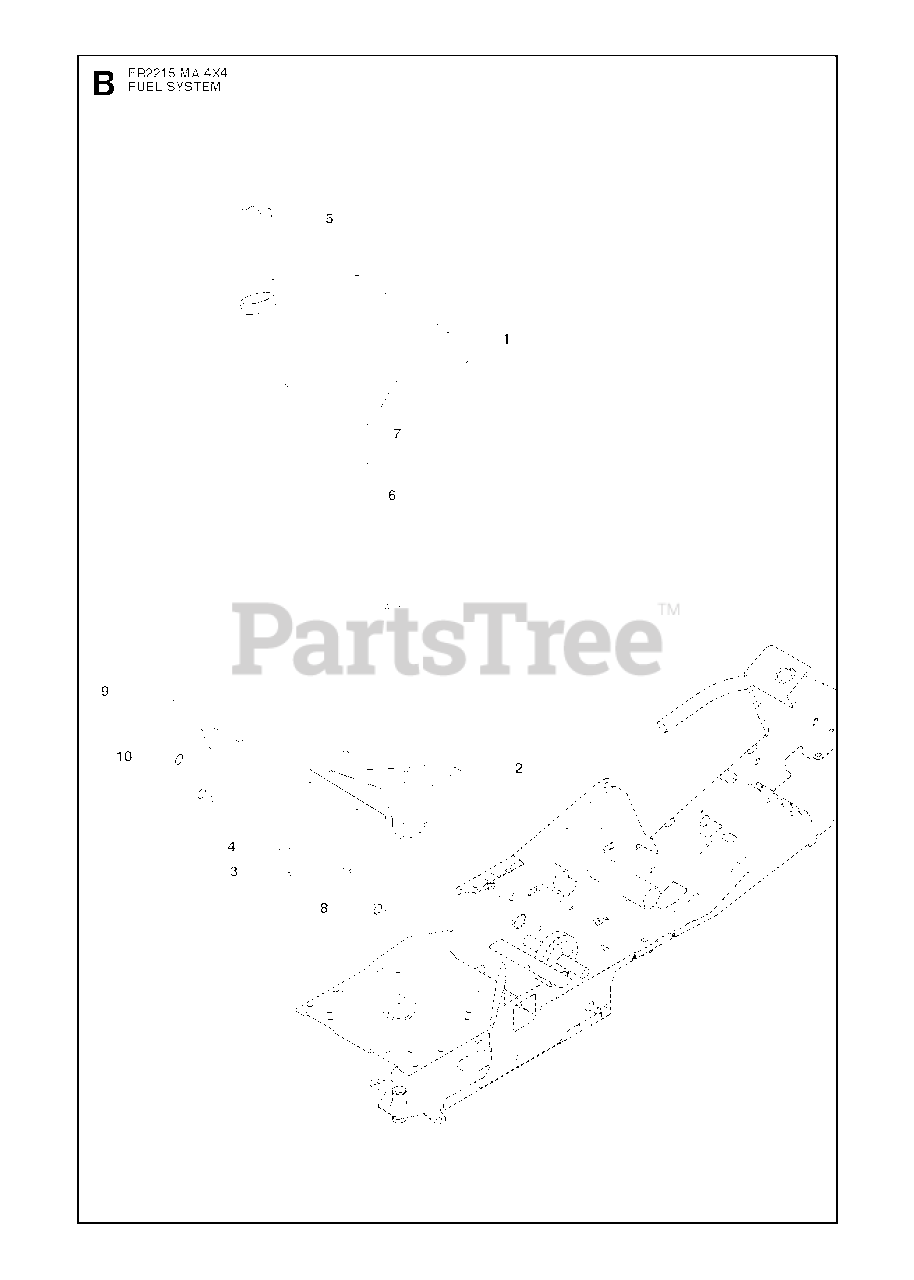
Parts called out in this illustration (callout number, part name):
3	LOCKNUT M6
4	WASHER
10	SCREW M10X25
